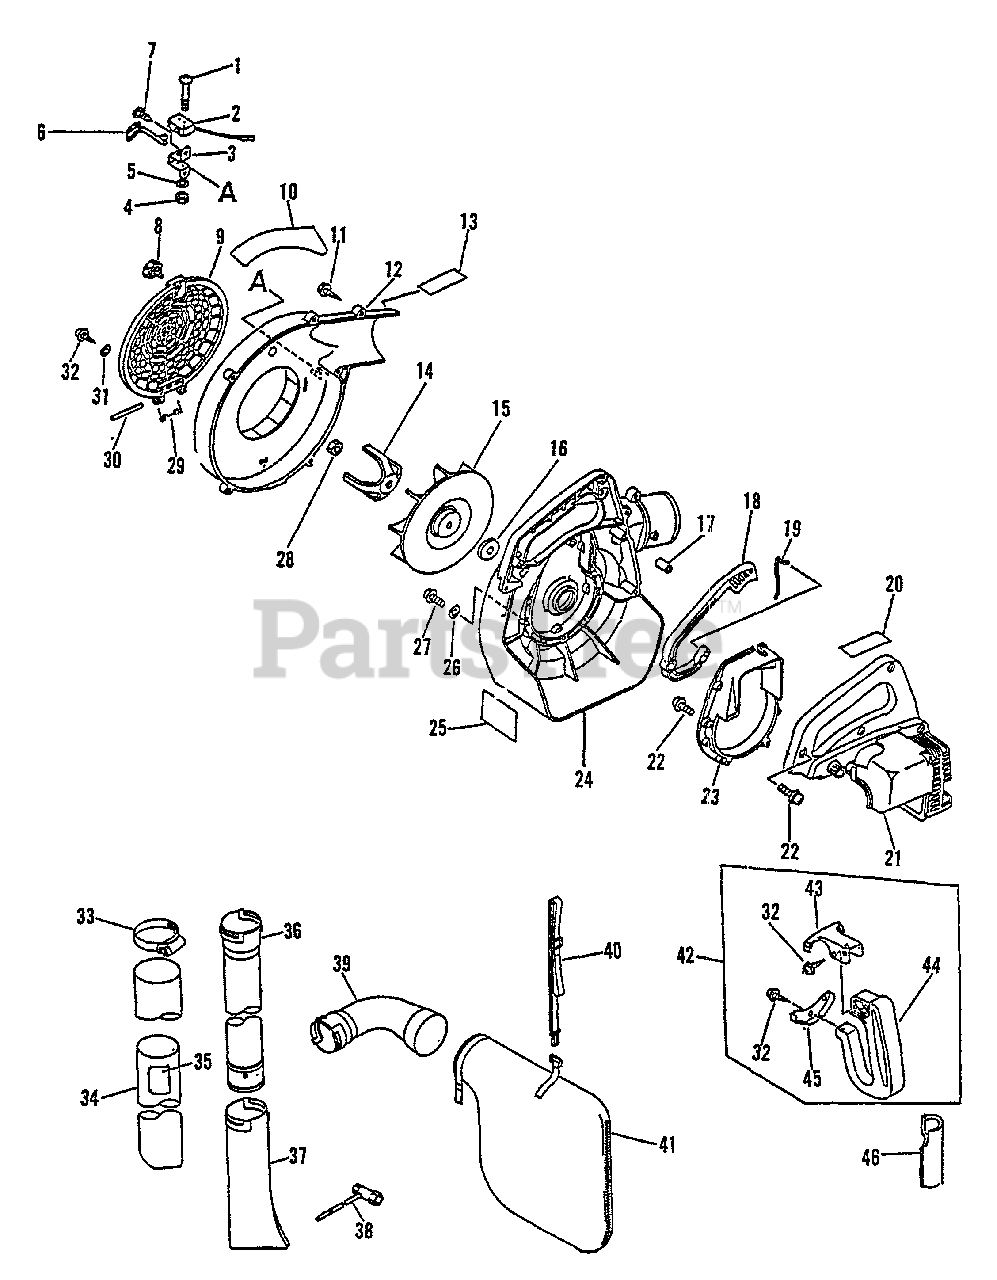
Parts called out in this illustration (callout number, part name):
1	SCREW
2	IGNITION SWITCH ASSY
3	BRACKET, SWITCH
5	LOCKWASHER
6	ACTUATOR
7	SCREW 5×10
8	THUMBSCREW
9	SHIELD, DEBRIS
10	LABEL, CAUTION
11	SCREW, TAPPING 5×20
12	COVER, FAN - LEFT
13	LABEL, ES-2000
14	SHREDDER
15	FAN
17	TUBE, RETAINER
18	TRIGGER, THROTTLE
19	ROD, THROTTLE
20	LABEL - CAUTION -- HOT
21	COVER, ENGINE
22	SCREW 4×18
23	BRACKET, ENGINE
24	COVER, FAN - RIGHT
25	LABEL - CAUTION
27	SCREW 4×22
29	SPRING, COIL
30	PIN, INTAKE COVER
32	SCREW 5×14
34	TUBE, VACUUM
35	LABEL, MODEL
36	TUBE, BLOWER - STRAIGHT
37	NOZZLE - FAN HEAD
38	WRENCH
41	BAG, DUST
42	HANDLE ASSY, SIDE
43	BRACKET, UPPER HANDLE
44	HANDLE
45	BRACKET, LOWER HANDLE
46	GRIP, HANDLE
